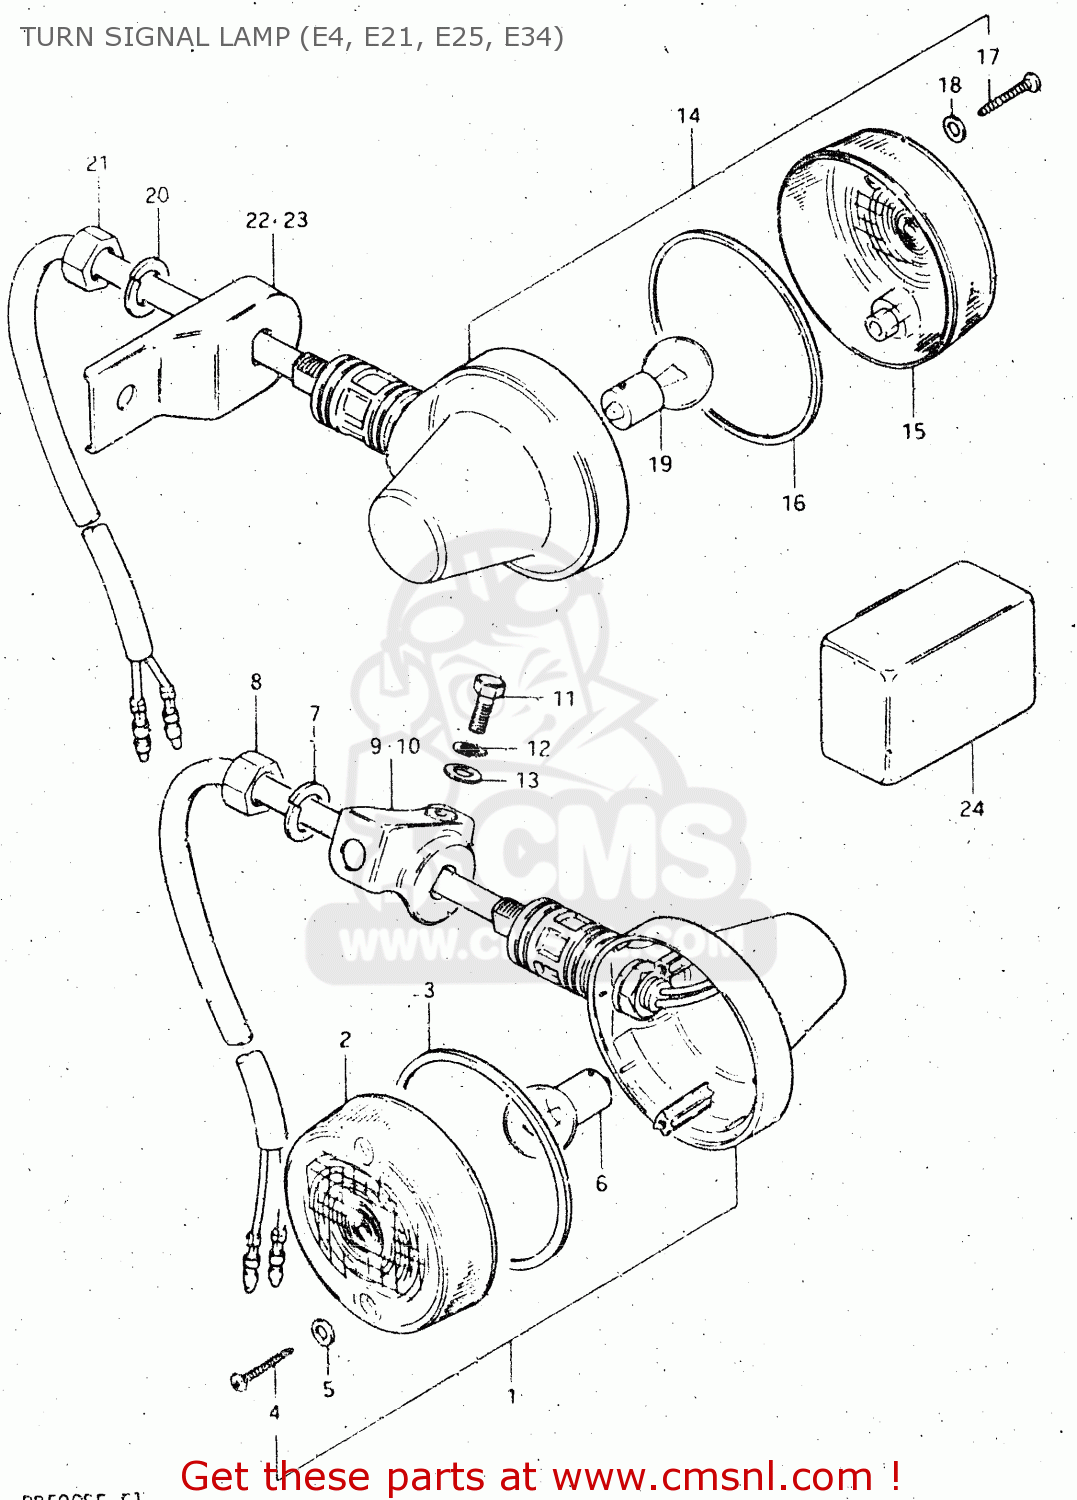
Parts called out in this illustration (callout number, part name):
1	LAMP ASSY,FR T
2	LENS
3	GASKET (NAS)
4	SCREW TAPP.
5	GASKET (NAS)
6	BULB(6V/10W,STANLEY,A4117)
7	WASHER
8	NUT 12MM
9	BRACKET,TURN SIGNAL LAMP
10	BRACKET,TURN SIGNAL LAMP
11	BOLT
12	LOCK WASHER
13	WASHER
14	LAMP ASSY,RR TURNSIGNAL
15	LENS
16	GASKET (NAS)
17	SCREW TAPP.
18	GASKET (NAS)
19	BULB(6V/10W,STANLEY,A4117)
20	WASHER
21	NUT 12MM
22	BRACKET,REAR TURN SIGNAL
23	BRACKET,REAR TURN SIGNAL
24	RELAY, TURN SIGNAL
